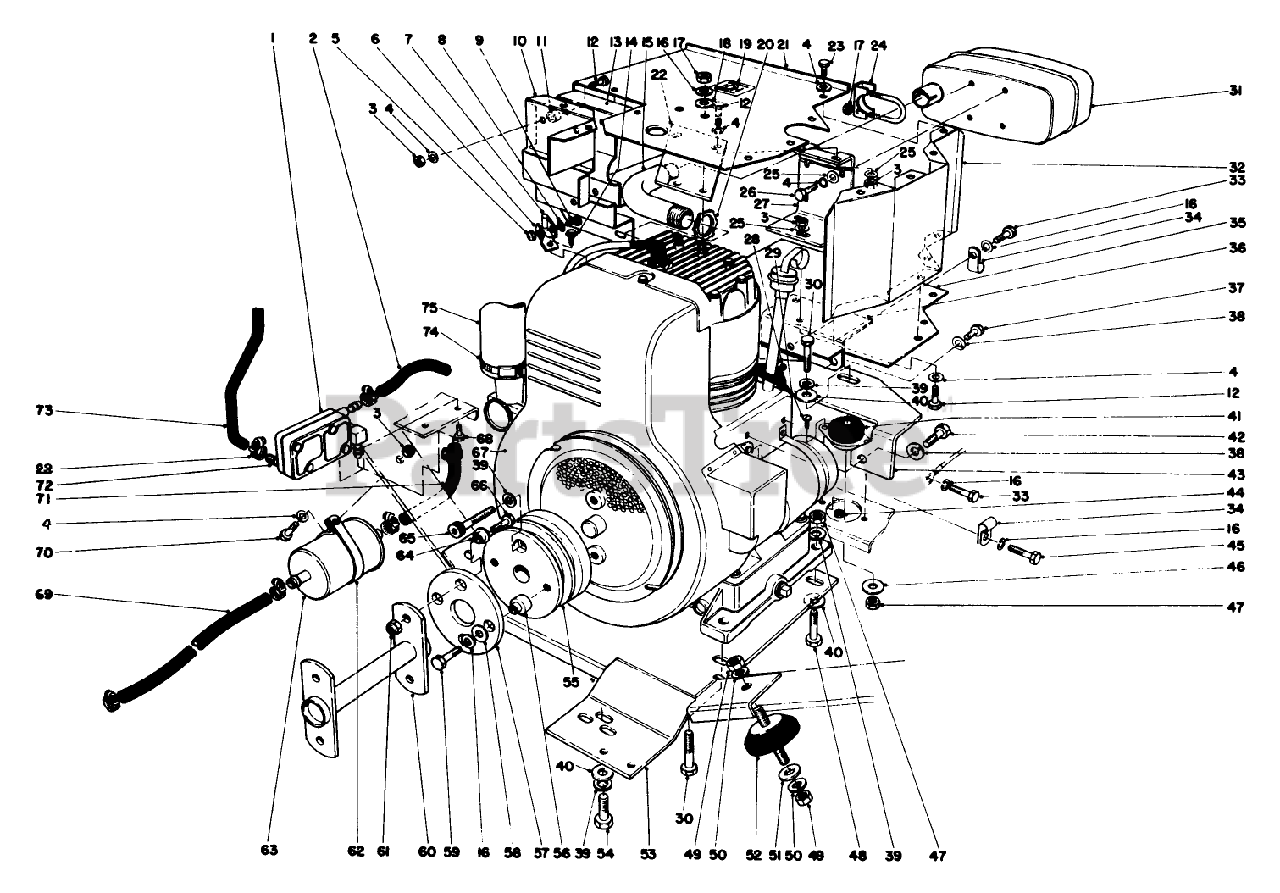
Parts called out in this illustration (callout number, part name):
1	FUEL PUMP
2	PULSE LINE
3	NUT-HEX
4	WASHER-LOCK
5	NUT-HEX
6	BODEN CLIP BRKT
7	CLAMP-BODEN
8	WASHER-LOCK
9	SCREW-PPH
10	REAR SHIELD WA B
11	SPACER HEAT SHIELD
12	SCREW-HH
13	Shield Exhaust
14	SCREW
15	EXHAUST PIPE
16	Lockwasher
17	NUT-HEX
18	WASHER-PLAIN
19	Decal-Hot
20	Locknut
21	Top Heat Shield
22	MUFFLER BRACKET B
23	SCREW THD 1/4 20 5/8
24	MUFFLER CLAMP
25	WASHER-FLAT
26	SCREW-HH
27	MUFFLER BRKT B
28	CLAMP-HOSE
29	10-24 X 5/8 PAN HD MS
30	SCREW-HH
31	Muffler
32	LH SIDE HT SHIELD B
33	SCREW-HH
35	Bottom Heat Shield
36	Bracket Heat Shield
37	SCREW-HH
38	WASHER-LOCK
39	WASHER-LOCK
40	WASHER-FLAT
41	RUBBER MOUNT
42	SCREW-HH
43	REAR ENGINE MT B
44	NUT-LOCK, NI
45	SCREW-HH
46	WASHER
47	NUT-HEX
48	SCREW-HH
49	NUT-HEX
50	WASHER-LOCK
51	WASHER-FLAT
52	RUBBER MOUNT
53	ENGINE BASE WA
54	SCREW-HH
55	ENGINE PULLEY BO
56	SPACER-RUBBER COUPLNG
57	Coupling Rubber
58	WASHER-FLAT
59	SCREW-HH
60	Drive Coupling
61	NUT-HEX
62	HOSE CLAMP
63	FiIter Gas
64	SPACER-COUPLING
65	SCREW-HSH
66	SCREW-HH
67	Engine Briggs & Stratton (Model No. 326437)
68	Screw-Outlet
69	HOSE-FUEL
70	SCREW-HH
71	HOSE-FUEL
72	FITTING
73	FUEL LINE
74	CLAMP-HOSE
75	AIR CLEANER HOSE
